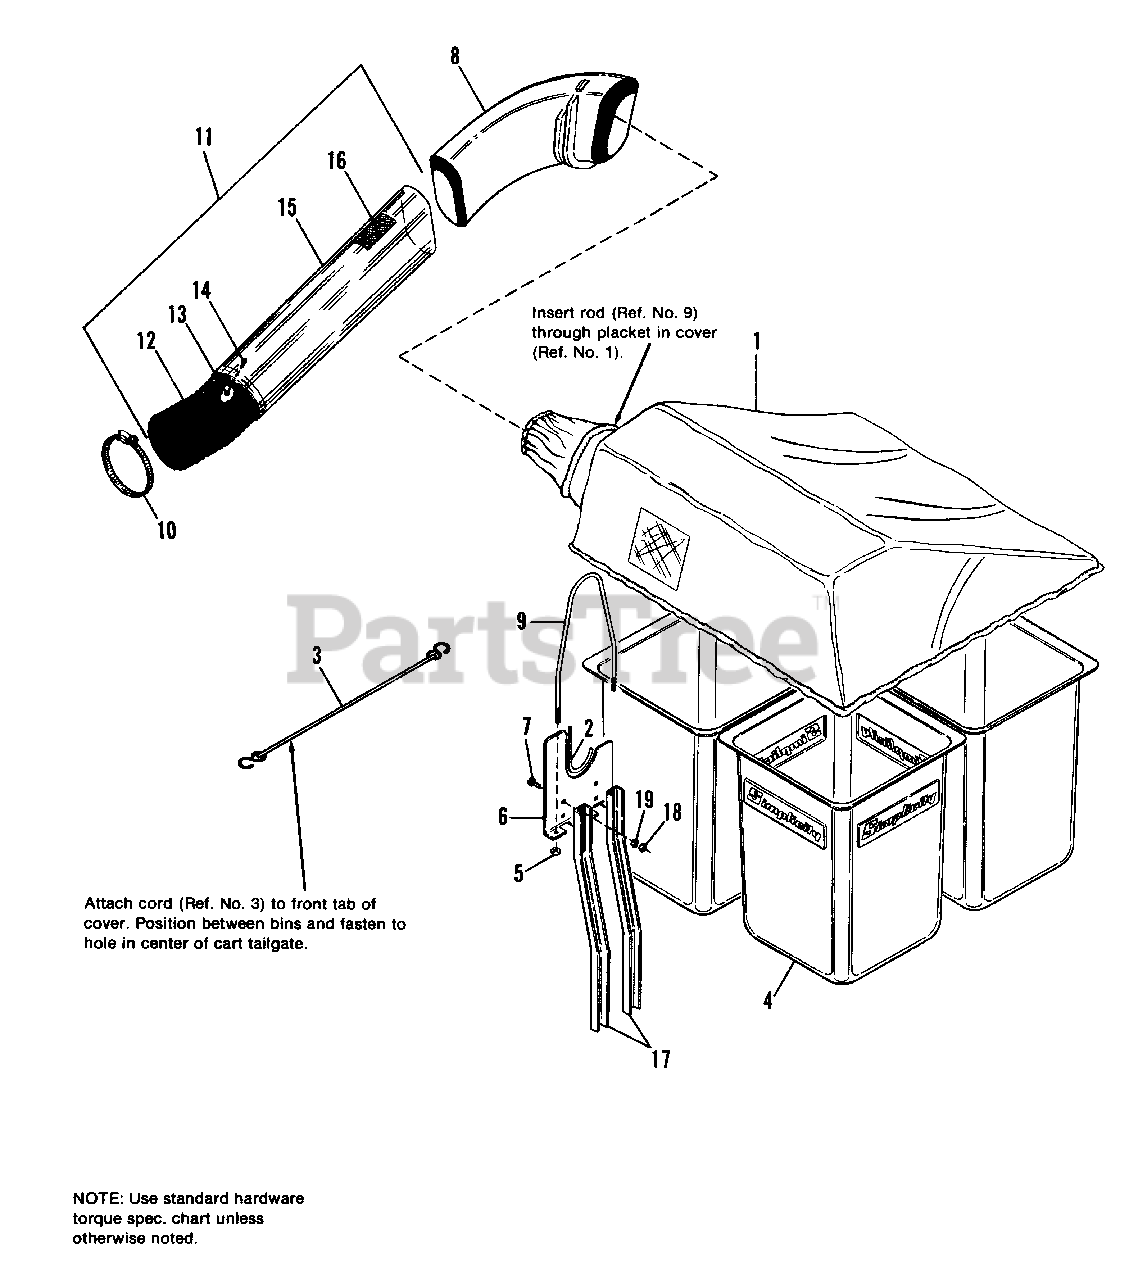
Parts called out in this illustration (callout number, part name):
4	BASKET, Grass
5	NUT, Hex, Centerlock, 5/16-18
6	BRACKET, Saddle
7	CARRIAGE BOLT, 1/4-20 x 5/8
9	CLAMP, Elbow
11	TUBE ASSY., (Incl. Ref. Nos. 12-16)
12	HOSE, 6" I.D.
13	WASHER, Rivet
16	DECAL, Cleaning Instructions
17	CHANNEL, Support
18	NUT, Hex, 1/4-20
19	LOCKWASHER, Spring, 1/4
